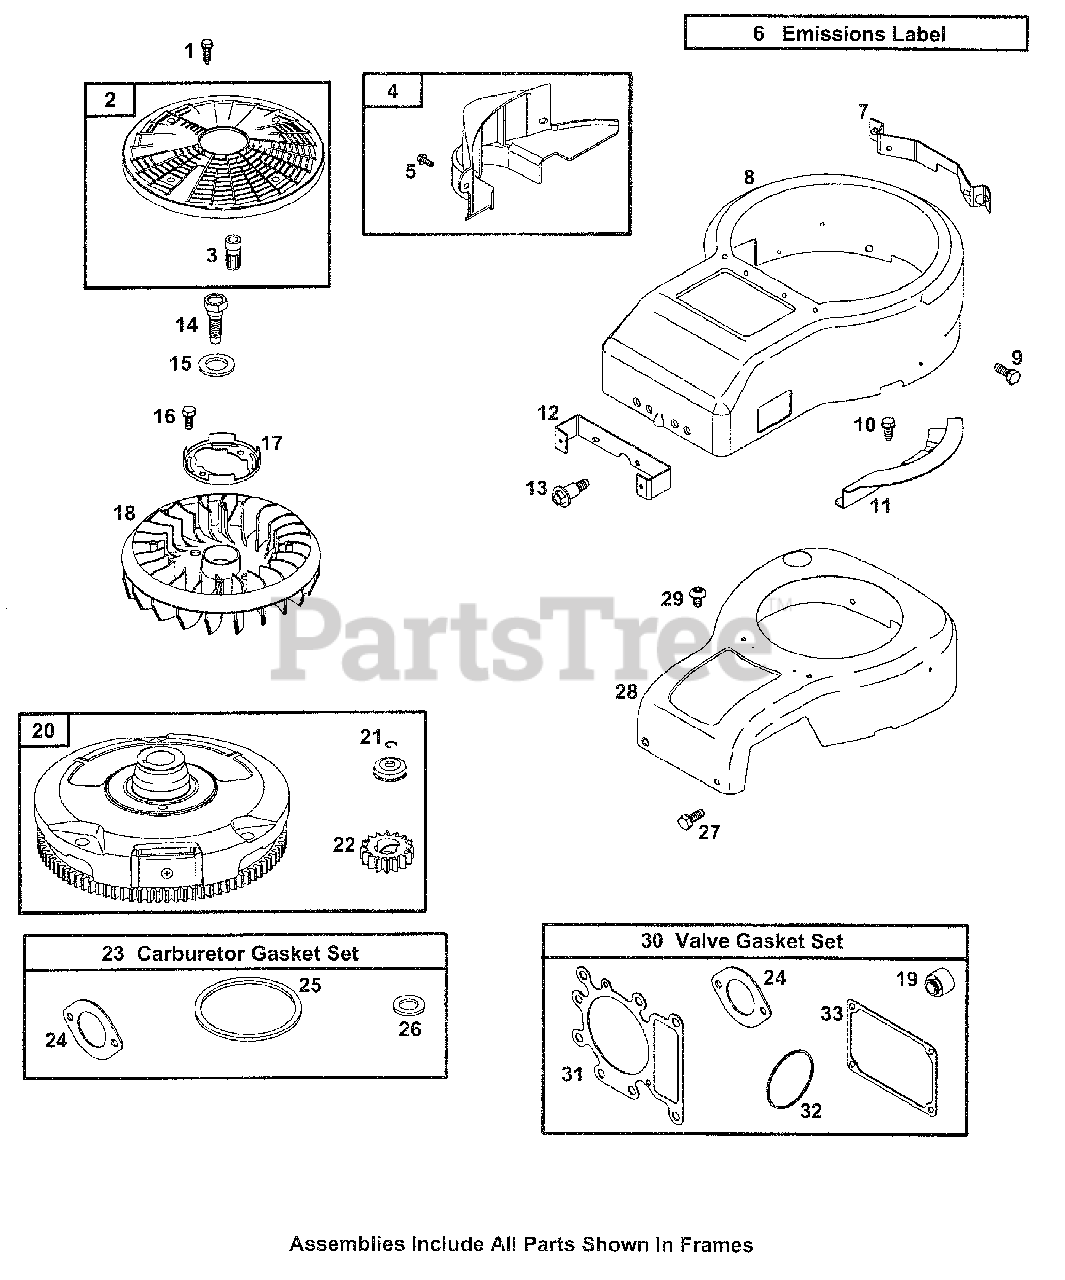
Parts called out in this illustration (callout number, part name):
1	Screw (Rotating Screen)
2	Rotating Screen
4	Starter Drive Cover
5	Screw (Starter Drive Cover)
6	Emissions Label
7	Mounting Bracket
8	Blower Housing
9	Screw (Blower Housing)
10	Screw (Flywheel Guard)
11	Flywheel Guard
12	Mounting Bracket
13	Screw (Mounting Bracket)
14	Screw (Crankshaft Extension)
15	Washer (Flywheel)
16	Screw (Fan Retainer)
17	Fan Retainer
18	Flywheel Fan
19	Valve Seal
21	Retaining Ring
22	Pinion Gear
23	Carburetor Gasket Set
24	Intake Gasket
25	Float Bowl Gasket
26	Sealing Washer
27	Screw (Blower Housing Cover)
28	Blower Housing Cover
29	Screw (Blower Housing Cover)
30	Valve Gasket Set
31	Cylinder Head Gasket
32	O-Ring Seal (Intake Manifold)
33	Rocker Cover Gasket
